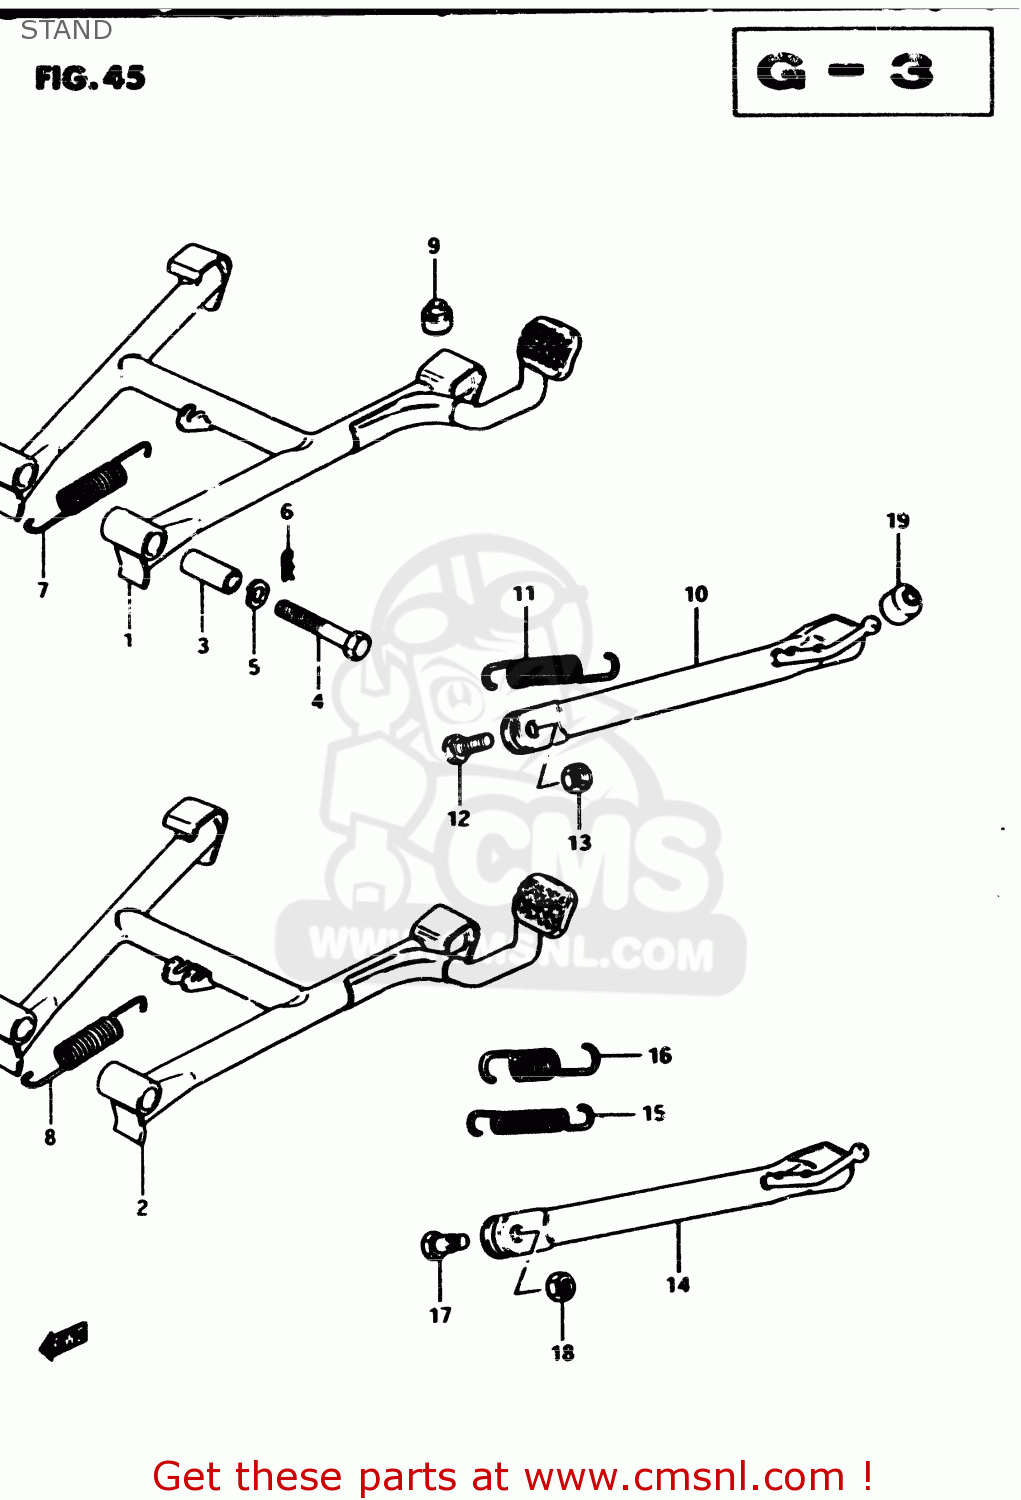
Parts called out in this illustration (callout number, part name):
1	STAND,CENTER
2	STAND, CENTER
3	SPACER(10X16X38.8)
4	BOLT
5	LOCK WASHER
6	CLIP
7	SPRING
8	SPRING
9	CUSHION
10	STAND,SIDE
11	SPRING
12	BOLT(10X30)
13	NUT
14	STAND, PROP
15	SPRING
16	SPRING, OUTER
17	BOLT L:30
18	NUT
19	CUSHION
